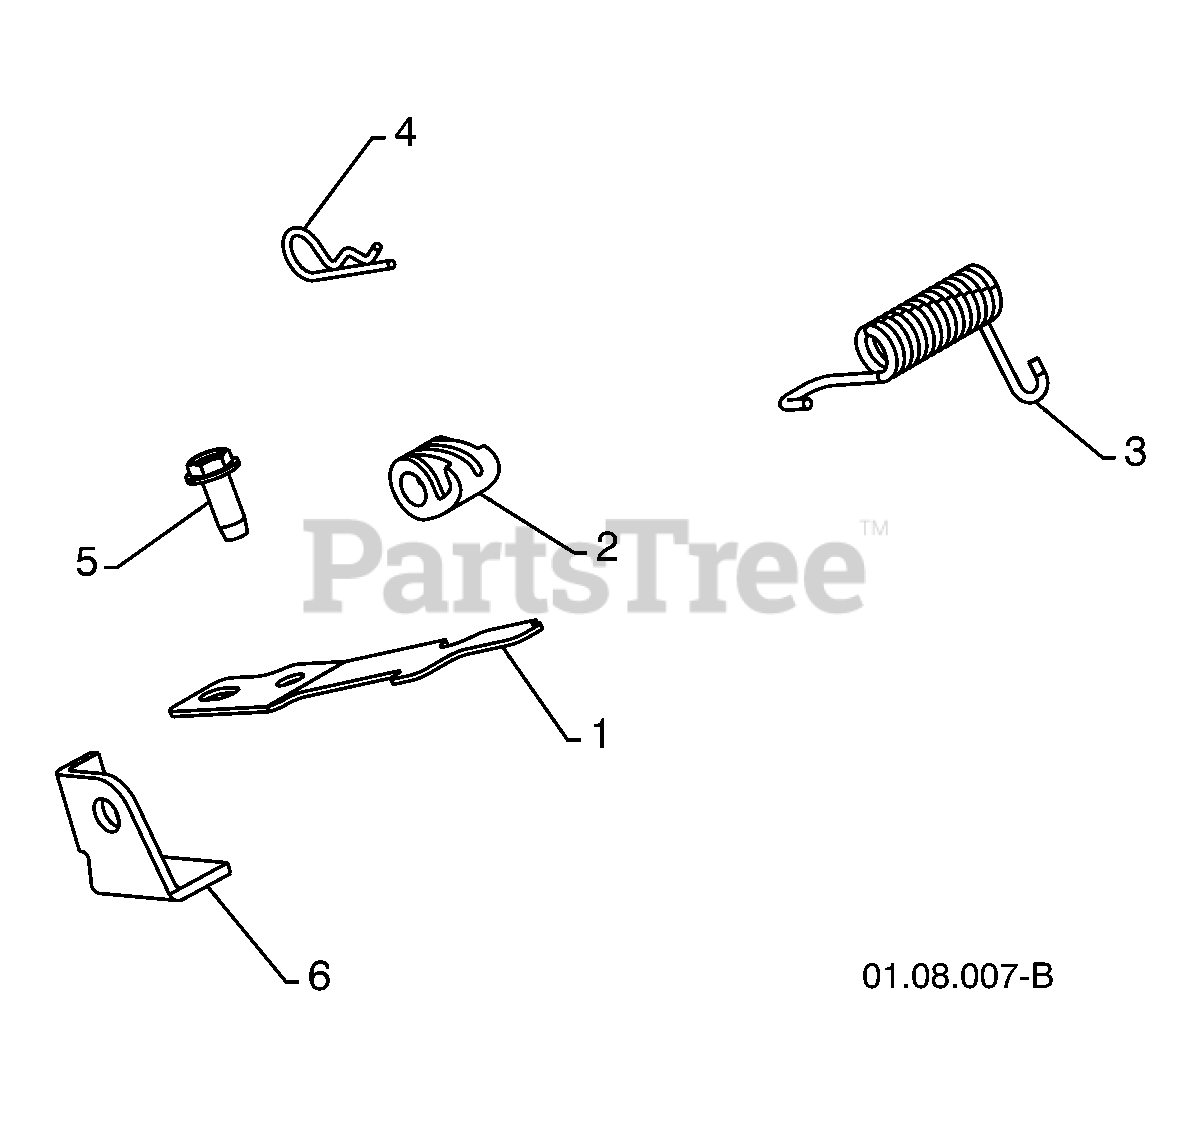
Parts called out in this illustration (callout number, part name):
1	INTERLOCK SPRING
2	INTERLOCK CAM
3	TORSION SPRING
5	SCREW 1/4--20 X .625
6	INTERLOCK STOP
